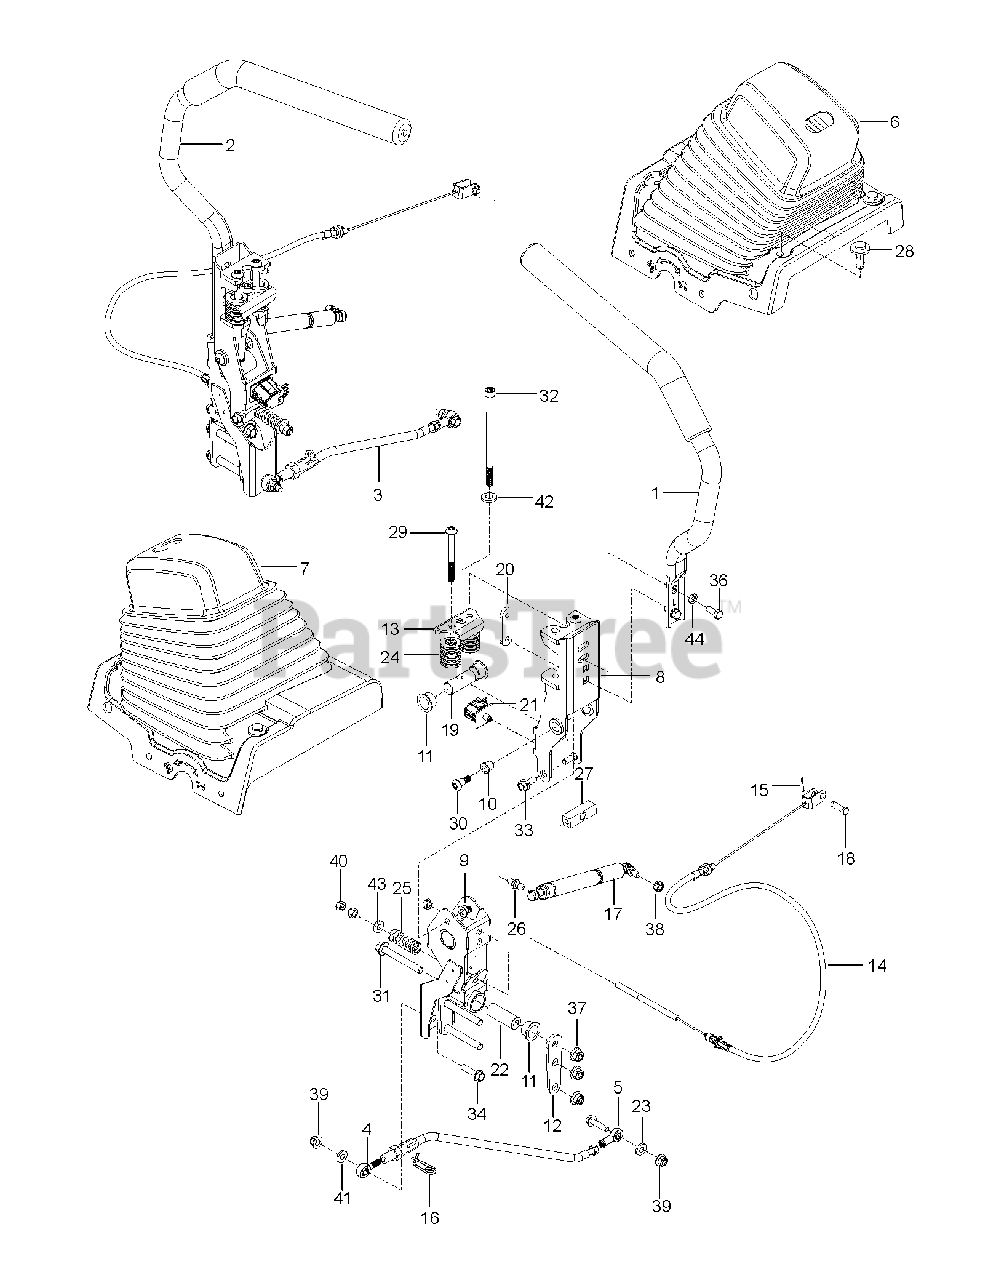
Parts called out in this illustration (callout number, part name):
1	Drive Lever Assembly, LH
2	Drive Lever Assembly, RH
3	ROD.ASM.CONTROL.PZ.4400.LH
4	ROD.END.MALE.LH.THREAD
5	Joint Heim, Feml.516.R
6	KIT.SERVICE.LEVER.BELLOW.LH
7	KIT.SERVICE.LEVER.BELLOW.RH
8	CARRIER.PNT.WELD.UPPER.LH.EDIP
9	CARRIER.PNT.WLDMT.LOWER.EDIP
10	BEARING.FLG.3/8.SHAFT.1/2.HSG
11	BEARING, FLANGE
12	BRACKET.PNT.CONTROLS.MTG.EDIP
13	BRACKET.RETAINING.SPRING
14	Parking Brake Cable
15	RETAINER CLIP
16	CLIP.RETAINER.CONTROLS
18	PIN.CLEVIS.5/16.DIA.3/4.USABLE
21	SWITCH.SNPMNT.DELTA.NCNC.PZREF
22	SPACER.PIVOT
23	SPACER.7_16OD;5_16ID;STEP.UP
24	SPRING 1.25"ODX1.5"L
25	SPRING, BRAKE ROD
26	STUD.BALL.10MM
27	CABLE.YOKE.PARK.BRAKE
28	RIVET.PUSH.PIN.0.25IN.HOLE
29	SCREW.SHCS.5/16-18 X 3-1/2"
30	SCREW.SHLDR.3/8 X 1/2.5/16-18
31	HHFS 3/8-16 X 3 GRD 5 ZD
32	SCREW.SHCS.3/8-16 X 6L.ZY
33	BOLT, SHOULDER
34	HHFS 5/16-18 X 1.25 TPBLT GD 5
36	HCS 5/16C X 3/4
37	NUT 3/8-16 HEX FLG NYLOC ZD
38	NUT 5/16C CENTERLOCK
39	5/16-18 NYLOC FLANGE NUT
41	WASHER
42	WASHER, 3/8 THICK
43	WASHER 5/16 FLAT
44	WASHER 5/16 LOCK
